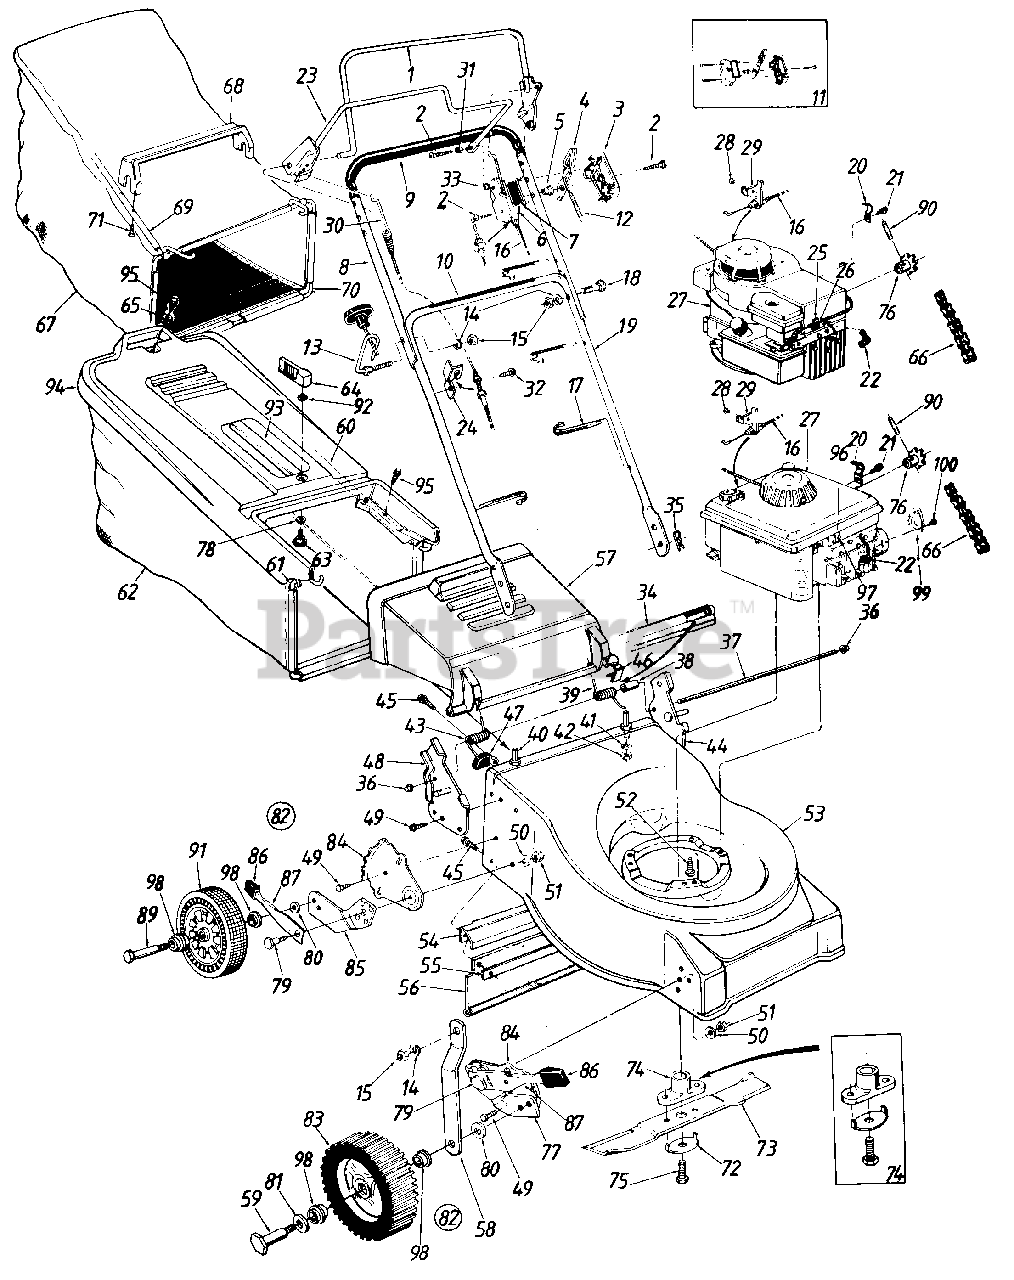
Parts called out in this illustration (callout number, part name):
1	Control Handle Ass'y.
2	Truss Mach. B-Tap Scr. #12 x 1.5" Lg.
3	Control Panel Half
4	Throttle Control Lever
5	Control Disc Pin
6	Clutch Panel Half
7	Control Label-Throttle
8	Upper Handle (Painted)
9	Grip
10	Instruction Label-Handle
11	Control Housing Comp.
12	Throttle Wire-58" Lg.
13	Rope Guide Bolt
14	L-Wash. 5/16" I.D.
15	Hex Nut 5/16-18 Thd.
16	Control Cable-43" Lg.
17	Cable Tie
18	Curved Carriage Bolt 5/16-18 x 1.38" Lg.
19	Lower Handle (Painted)
20	Cable Clamp
21	Hex B-Tap Scr. #10 x .38" Lg.
22	Spark Plug Boot
23	S.P. Bail Ass'y.
24	Cable Mounting Brkt.
25	Cable Clamp
26	Hex AB-Tap Scr. #8 x .5" Lg.
27	Engine
28	Pop Rivet .156" Dia.
29	Cable Bracket
30	Drive Cable-47" Lg.
31	Spacer.23" I.D.
32	Hex Wash. AB-Tap Scr. 5/16" x .75" Lg.
33	Spr. Wash. .206" I.D.
34	Seal-Extrusion
35	Int. Cotter Pin 5/16" Dia.
36	Cap Speed Nut
37	Hinge Pin 17.75" Lg.
38	Spacer.255" I.D.
39	Torsion Spring-L.H.
40	Shld. Pin 3/8-24 x 1.43" Lg.
41	L-Wash. 3/8" I.D.
42	Hex Jam Nut 3/8-24 Thd.
43	Torsion Spring-R.H.
44	Handle Brkt. Ass'y.-L.H.
45	Torx Mach. AB-Tap Scr. 1/4 x .62" Lg.
46	Deflector Plug
47	Corner Plug
48	Handle Brkt. Ass'y.-R.H.
49	Hex L-Wash. AB-Tap Scr. 1/4 x .62" Lg.
50	Bell-Wash. .39" I.D. x 1.38" O.D.
51	Hex Nut 3/8-16 Thd.
52	Hex TT-Tap Scr. 3/8-16 x 1"
57	Rear Chute Deflector
58	Link 5.06" Lg.
59	Front Axle Bolt
62	Grass Bag
63	Shld. Bolt .342" Dia. x .268"
64	Grass Catcher Locking Knob
65	Fl-Wash. .281" I.D.
66	#48 Chain 1/2" Pitch 50 Links (Endless)
67	Grass Bag
68	Bag Handle
70	Front Catcher Frame
71	Hex AB-Tap Scr. #12 x 1.25"
72	Blade Bell-Wash. .44" I.D. x 2.38"
73	21" Blade
74	Blade Adapter Kit
75	Hex Bolt 3/8-24 x 1.5" Lg.
76	10 Tooth Sprocket Ass'y.
77	Pivot Bar-R.F. & L.R.
78	Bowed Washer
79	Shld. Bolt .50" Dia. x .357"
80	Bell-Wash. .38" I.D. x .88" O.D.
81	Fl-Wash. .531 " I.D.
82	Front Height Adj. Ass'y. Comp.-L.F. & R.R.
83	Front Wheel Ass'y. Comp.
84	Index Plate
85	Pivot Bar-L.F. & R.R.
86	Spring Lever Knob
87	Spring Lever
89	Rear Axle Bolt
90	Spring Pin 3116" Dia.
91	Rear Wheel Ass'y. Comp.
92	Internal L-Wash. 1/4" I.D.
93	Hardtop Handle
94	Hardtop Bag Cover
95	Hex AB-Tap Scr. 1/4 x .62" Lg
96	Cable Clamp
97	Hex B-Tap Scr. #10 x .62" Lg.
98	Flanged Brg. .50" I.D.
99	Muffler Deflector
100	Hex Wash. AB-Tap Scr. #8 x .5" Lg.
